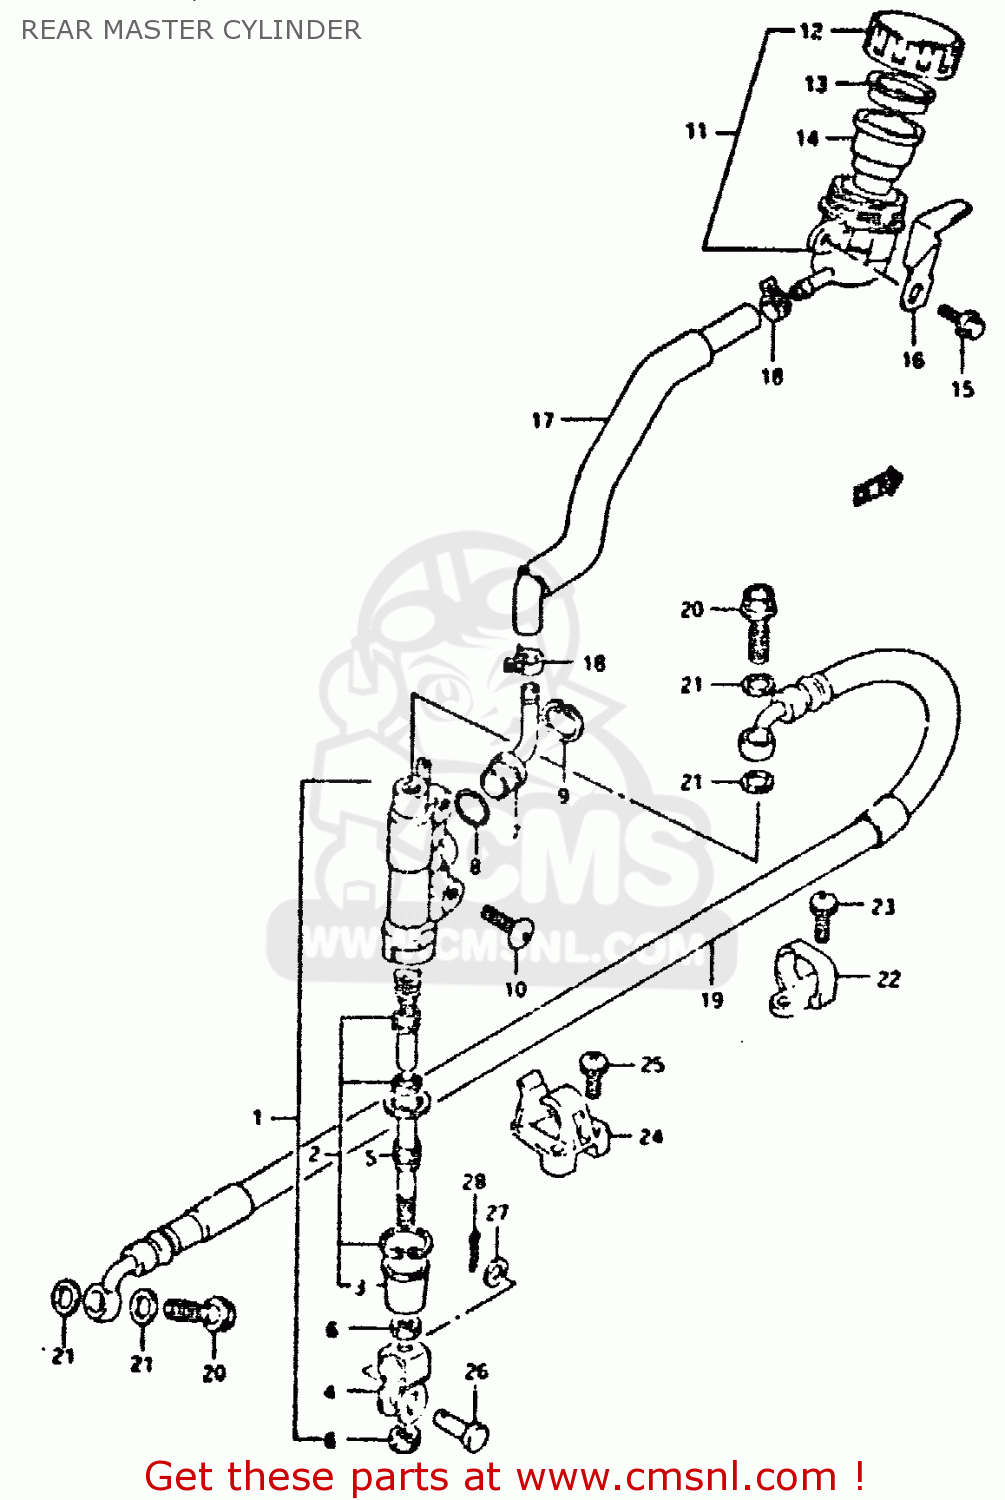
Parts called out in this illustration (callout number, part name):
1	CYLINDER ASSEMBLY,REAR MASTER
2	PISTON/CUP SET
3	BOOT
4	YOKE
5	ROD,PUSH
6	NUT
7	CONNECTOR
8	O RING
9	CIRCLIP
10	SCREW
11	TANK ASSY,RR BRAKE RESERVOIR
12	CAP
13	PLATE
14	DIAPHRAGM
15	BOLT
16	GUARD,RSVR TANK CAP
17	HOSE COMP,RESERVOIR TANK
18	CLIP
19	HOSE,RR BRAKE
20	BOLT UNION
21	WASHER(10X15X1.5)
22	GUIDE,RR BRAKE HOSE
23	SCREW
24	GUIDE,RR BRAKE HOSE
25	SCREW
26	PIN(8X20)
27	WASHER(8.5X13X1.6)
28	PIN 20X15
